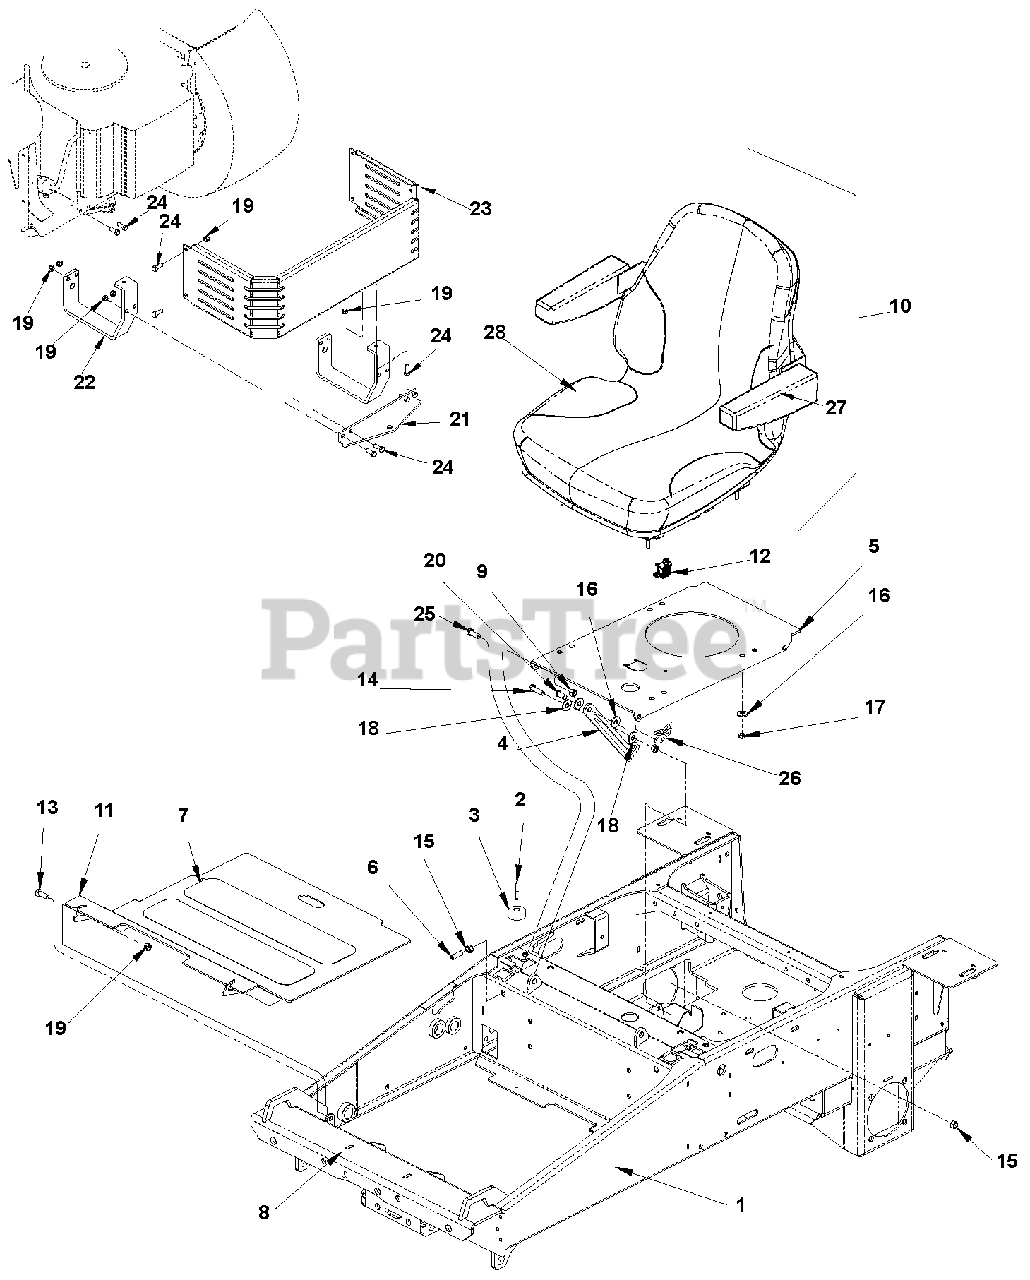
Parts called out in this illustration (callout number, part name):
1	Weldment, Unibody Frame w/Decals
2	Rivet, 3/16 x .500 Pop
3	Bumper, Rubber .625 x 1.50 DIA
4	Bar - Seat Lock
5	Plate, Seat
6	Set Screw, 3/8-16 x 3/4 ALHD CUP
7	Traction Tape, 4 x 18
8	Traction Tape, 2.5 x 21.5
9	Locknut, 3/8-16 Crown
10	Seat, Full Suspension (Includes items 12, and 27 - 31)
11	Foot Plate
12	Seat Switch S/O
13	Bolt, 3/8-16 x 1.00 Hex 5
14	Bolt, 3/8-16 x 1.25 Hex 5
15	Nut, 3/8-16 STD Hex Grade 5
16	Washer, .313 Reg. Flat
17	Locknut, 5/16-18 Crown
18	Washer, .375 Reg Flat
19	Locknut, 3/8-16 Crown
20	Pin, Clevis .375 x .750 x .516
21	Plate, Hitch
22	Arm, Hitch Support
23	Bumper Plate
24	Bolt, 3/8-16 X 1.00 Hex 5
25	Bolt, 1/2 x 1.06 x 3/8-16
26	Ring, Rue
27	Kit, Armrest Assembly
28	Kit, EverRide Cushion
